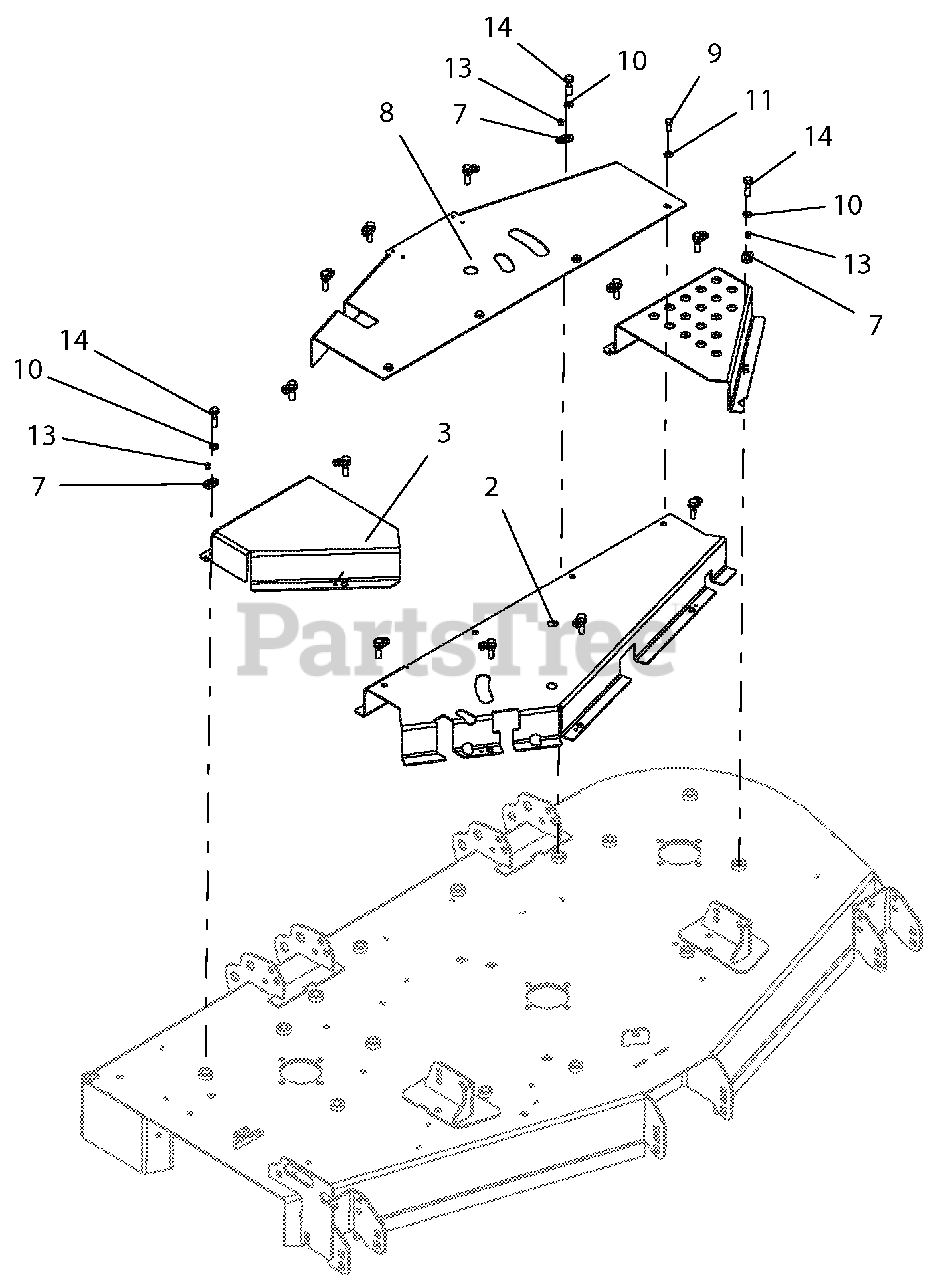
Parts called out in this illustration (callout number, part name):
2	WLDMT, FRONT BELT GUARD CE-60-BLACK
3	GUARD, RH PT200 CE BELT (BLACK)
7	KEEPER, BOLT
8	BRKT, REAR BELT GUARD CE-60 (BLACK)
9	BLT-HEX .25-20X.75 GR5 YWZC
10	LOCK, WSHR-EXT 0.391 X 0.628 X 0.036 YWZC
11	WSHR-FL-STL.281X.62X.065 YWZC
13	RVT-POP .187x.250 (#64) YWZC
14	BLT, HEX 0.38-16 X 1.25 GR5 CAPTIVE
